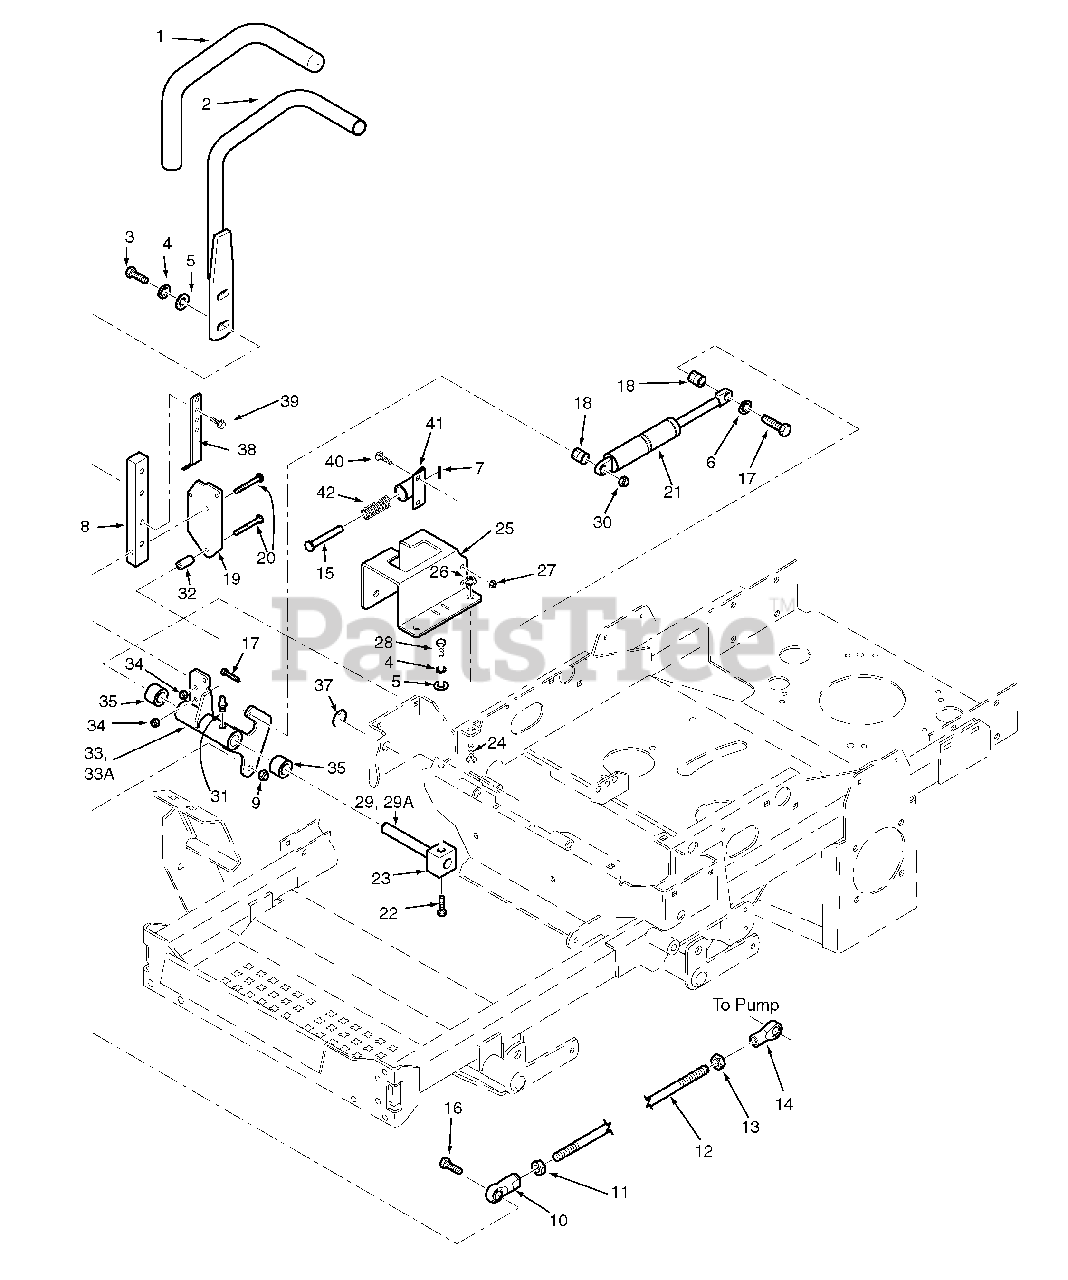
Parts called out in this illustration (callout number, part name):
1	Grip, Control Lever
2	Handle Bar
3	Bolt, Hex Head 3/8-16 x 1-1/4"
4	Lock Washer, 3/8"
5	Flatwasher, 3/8-.391 x .938 x .105
6	Flatwasher, 5/16-.375 x .875 x .083
7	Roll Pin, Spring 5/32 x 3/4"
8	Bar, Control Lever
9	Nut, Elastic Stop 3/8-16
10	Rod End, 3/8-24 RH Female
11	Nut, 3/8-24 RH Thread
12	Rod, Pump Control Linkage
13	Nut, 3/8-24 UNF-2B LH Thread
14	Rod End, 3/8-24 LH Thread
15	Pin Retainer
16	Bolt, Hex Head 3/8-16 x 1-1/2"
17	Bolt, Hex Head 5/16-18 x 1-3/4"
18	Spacer, Pump Dampener
19	Plate, Control Lever
20	Bolt, Hex Head 5/16-18 x 2"
21	Gas Damper
22	Bolt, Hex Head 3/8-16 x 1"
23	Block, Clamping
24	Bolt, Carriage, 5/16-18 x 3/4"
25	Control Plate - LH
25	Control Plate - RH
26	Nut, Serr., Flange, 5/16-18
27	Nut, Elastic Stop 1/4-20
28	Bolt, Hex Head 3/8-16 x 3/4"
29	Shaft, Steering Control
29A	Block, Clamp
30	Nut, Elastic Stop 5/16-18
31	Grease Fitting, 1/4-28 Self Tap
32	Spacer, Control
33	Control Lever Assy RH
33	Control Lever Assy LH
34	Nut, Elastic Stop 5/16-18
35	Bushing
36	Flatwasher, 1-1/4 x 49/64 x 16 Ga.
37	Retaining Ring, 3/4" Ext.
38	Bracket, Switch Actuator
39	Bolt, Hex Serr. Flange 5/16-18 x 3/4"
40	Bolt, Carr. 1/4-20 x 3/4"
41	Bracket, Control Return
42	Spring
43	Pin Retainer
